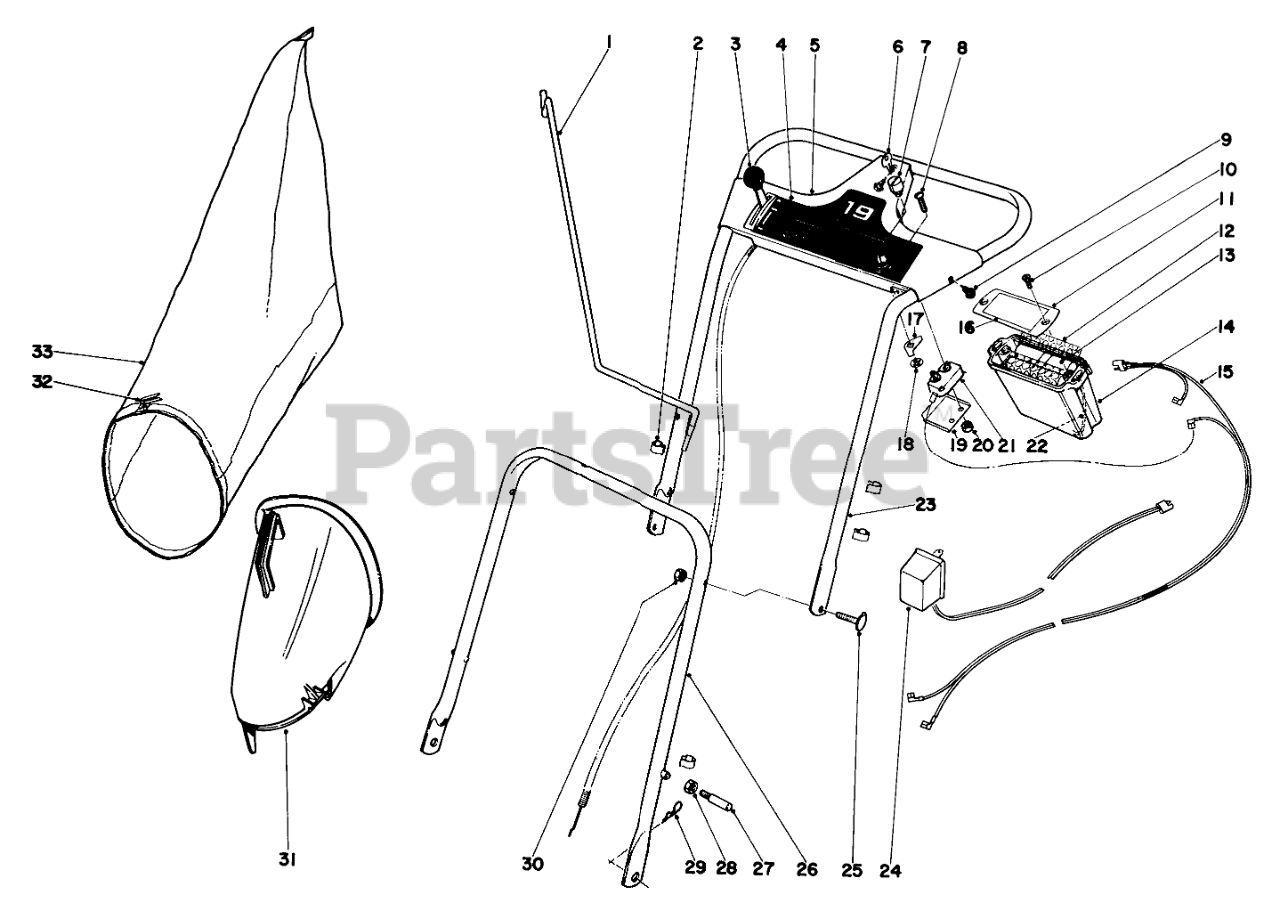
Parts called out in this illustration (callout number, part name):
1	Bag Hanger Rod
2	CONTROL WIRE CLIP
3	Throttle Control
4	Decal, Escutcheon Plate
5	Escutcheon Plate
7	Key Hsg.
9	SCREW-HWHTF
11	Cover
12	Spacer
13	Battery Pack
14	Container Pack
15	Wire Harness
16	Decal
19	Cover Switch
20	NUT-KEPS
21	Switch
22	Plug & Wire
23	Upper Handle
24	Charger
25	1-1/4 LG HANDLE SCREW
26	Lower Handle
27	Handle Pin
28	Nut
29	PIN-COTTER, HAIR
30	Nut
31	Bag Attachment
32	BAG CORD FASTENER
33	Flow Gauge
